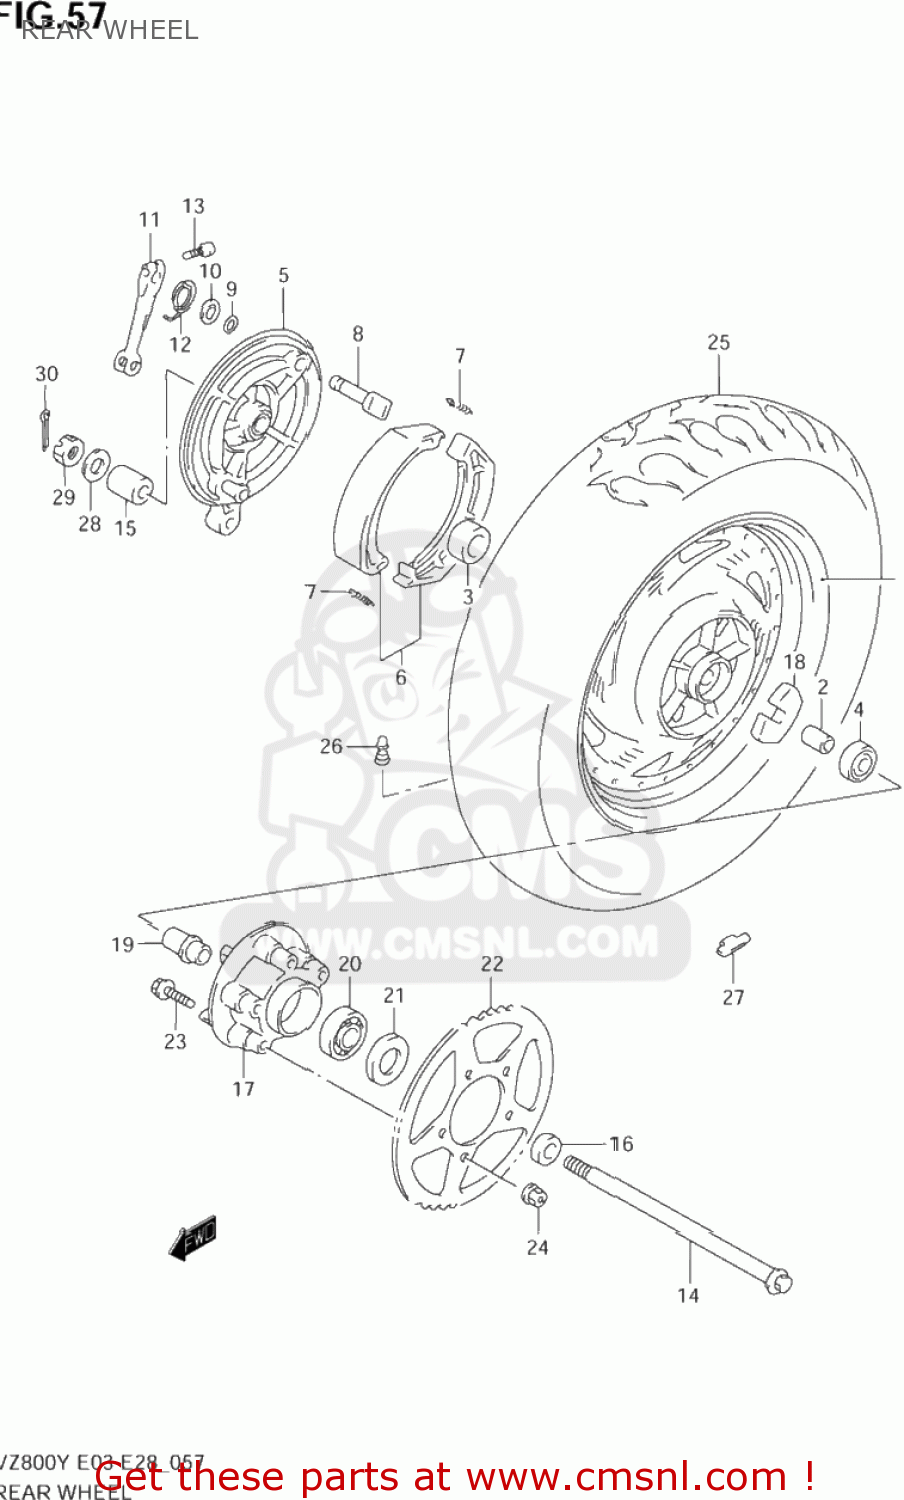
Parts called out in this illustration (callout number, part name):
1	WHEEL,RR(15M/CXMT3.50)
2	SPACER(17.5X25X70)
3	BEARING
4	BEARING
5	PANEL,RR BRAKE ANCHOR
6	SHOE SET,BRAKE (NAS)
7	SPRING,BRAKE SHOE
8	CAM,RR BRAKE
9	O RING(D:2.4,ID:14.8)
10	WASHER(15.5X24X1.6)
11	LEVER,RR BRAKE CAM
12	SPRING
13	BOLT
14	AXLE,RR
15	SPACER(17X33X35.3)
16	SPACER,RR AXLE,L
17	DRUM,RR SPROCKET MOUNTING
18	ABSORBER,RR HUB SHOCK
19	RETAINER,RR SPROCKET DRUM
20	BEARING(25X62X17)
21	SEAL,OIL(35X62X8)
22	SPROCKET,RR(NT:48-530)
23	BOLT
24	NUT
25	TIRE,RR(150/90 15M/C 74H)
26	VALVE ASSY,WHEEL RIM(TR412)
27	WEIGHT,BAL. 30
28	WASHER(16.2X30X2.6)
29	NUT
30	PIN, COTTER
